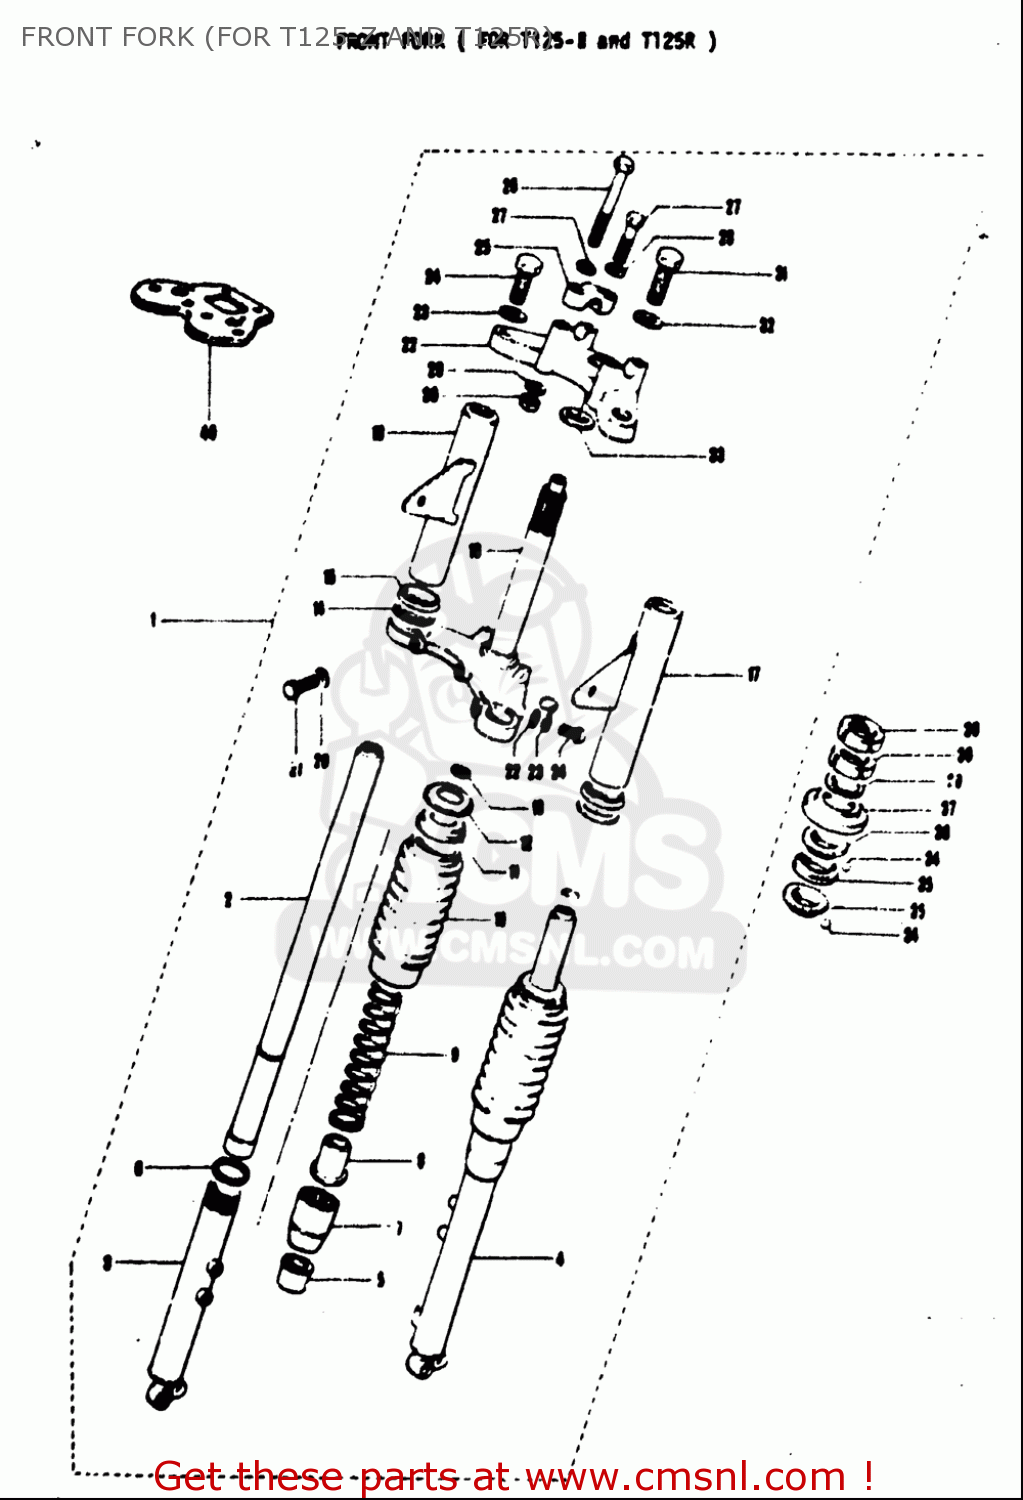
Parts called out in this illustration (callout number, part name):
5	GUIDE,FORK INNER TUBE
9	SPRING,FR FORK
13	O RING
19	CLIP,SPEEDOMETER CABLE
20	WASHER,LOCK
21	BOLT
23	WASHER,LOCK
24	BOLT,FR FORK(10X33)
25	HOLDER,HANDLEBAR
26	BOLT,HANDLEBAR CLAMP
27	BOLT
28	WASHER,LOCK
29	WASHER
30	NUT
31	BOLT,FR FORK(10X33)
36	LACE,STEERING OUTER UPR
